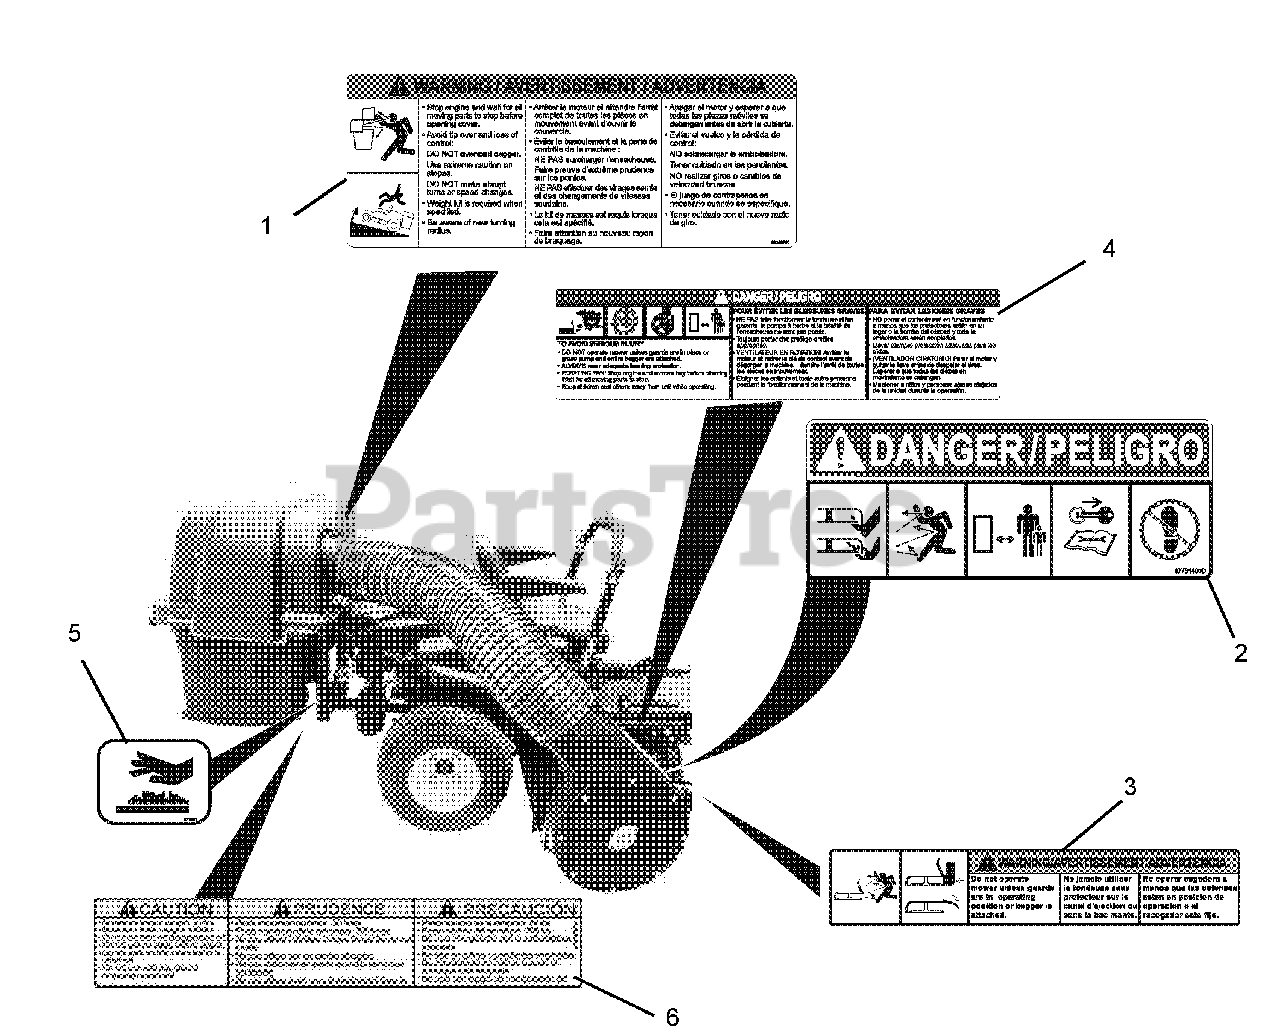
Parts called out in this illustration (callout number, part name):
1	Bagger Cover Decal
2	Mower Pan Danger Decal
3	Warning Decal
4	Grass Pump Caution Decal
5	Decal, Hot Surface
6	Decal, Caution
